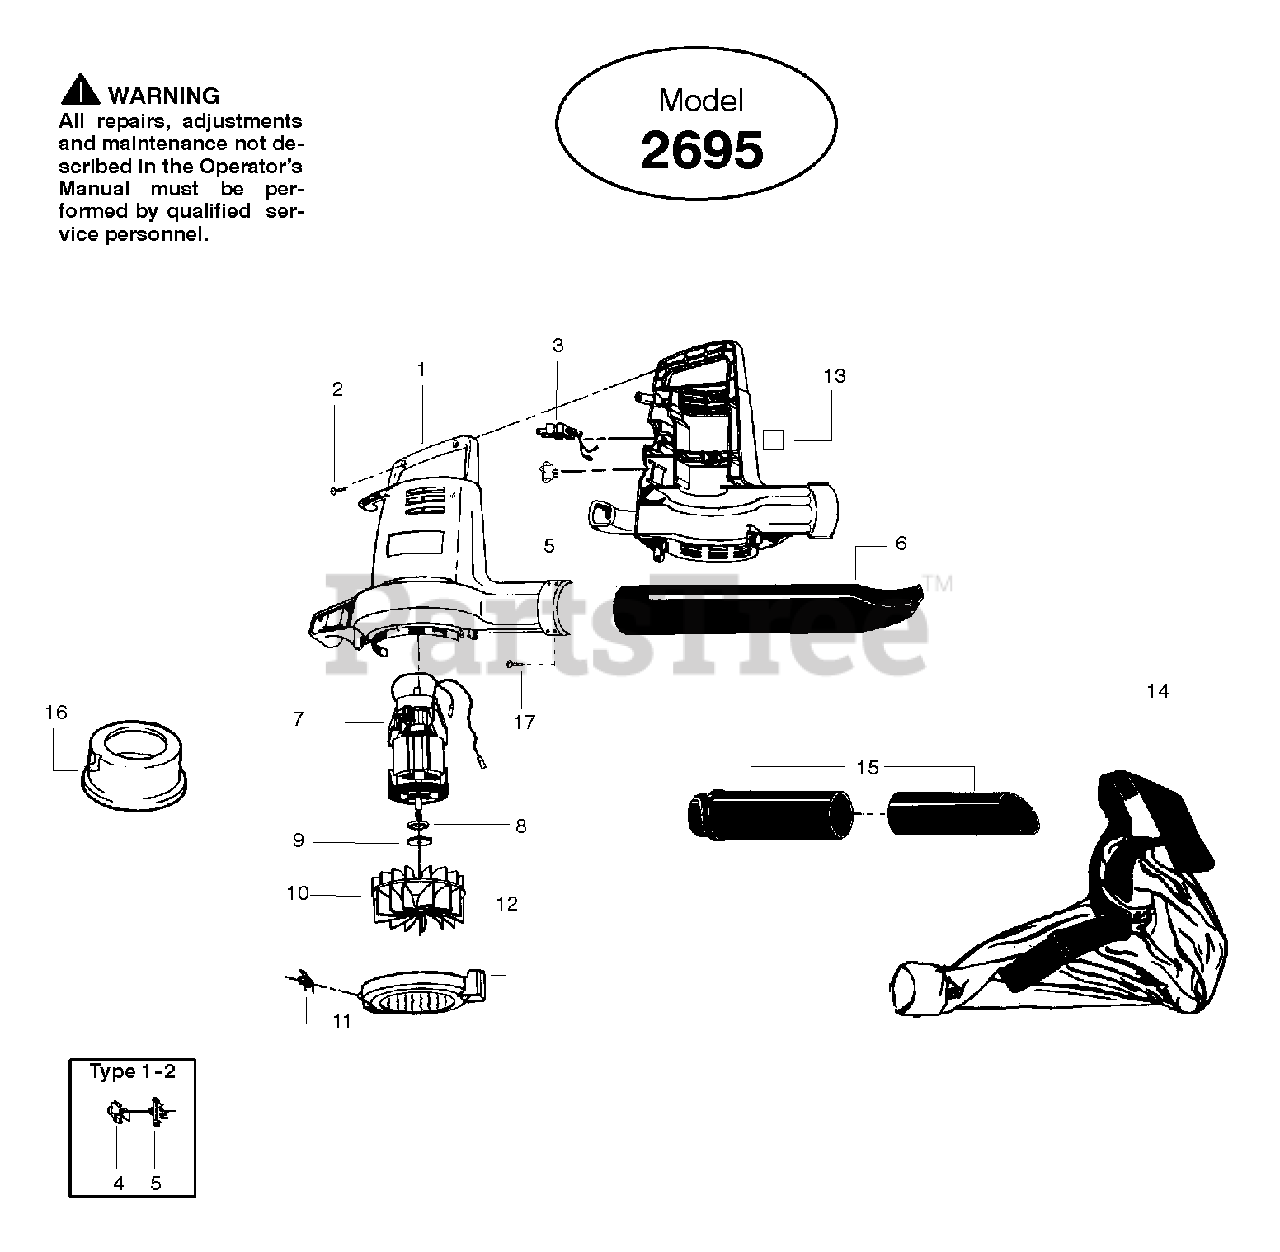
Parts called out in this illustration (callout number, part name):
1	Housing Set (Type 1,2)
1	Housing Set (Type 3)
3	Wire Harness (Type 1,2)
3	Wire Harness (Type 3)
4	Switch Cover(Type 1,2)
5	Switch (Type 1,2)
5	Switch (Type 3)
6	Blower (Tube w/Nozzle)
7	Motor Ass'y. Type 1
7	Motor Ass'y. Type 2,3
8	Spacer (Type 2,3 only)
10	Impeller
12	Assy-Cover Spring
13	Pad (Type 1 only)
14	Vacuum Bag Kit
15	Vacuum Tube Kit
16	Inlet Restrictor
